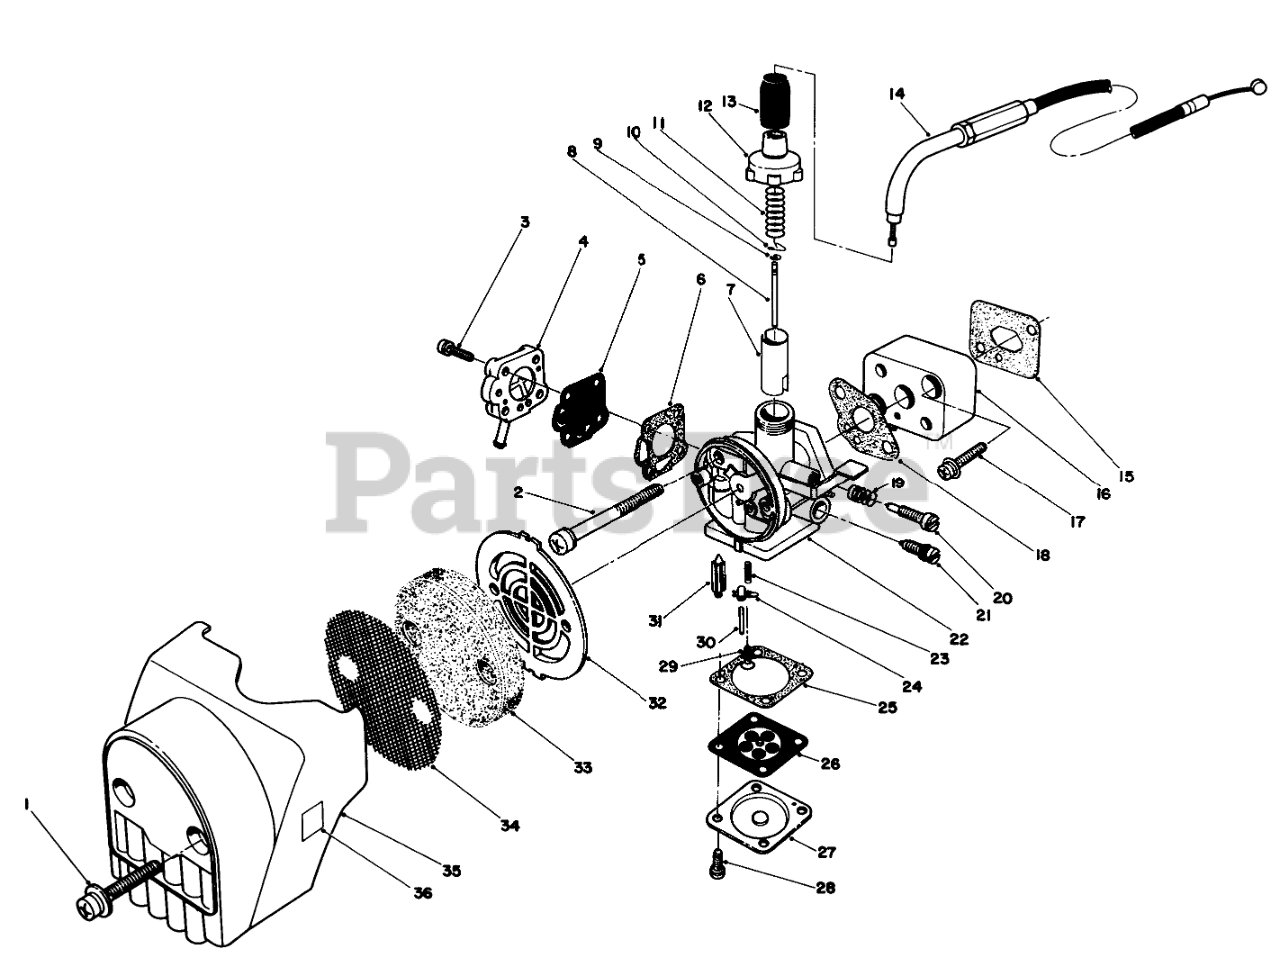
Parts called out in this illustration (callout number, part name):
1	Screw
2	SCREW W/ WASHER
3	SCREW W/ WASHER
4	Cover-Pump
5	Diaphragm-Pump
6	PUMP COVER GASKET
7	VALVE, THROTTLE
8	Jet Needle Assembly
9	Retainer
11	SPRING
13	AIR SEAL
14	WIRE, THROTTLE
15	GASKET,INSULATOR
16	INSULATOR
17	Screw & Washer
18	CARB. GASKET
19	ADJ. SCREW SPRING
20	SCREW
21	Needle-Main Jet
22	Carburetor Assembly (Incl. Ref. #3-13, 19-21, & 23-31)
23	VALVE SPRING
24	FLOAT ARM
25	DIAPHRAGM GASKET
26	Diaphragm-Main
27	DIAPHRAGM COVER
28	SCREW W/ WASHER
29	FLOAT SCREW
30	FLOAT PIN
31	FLOAT VALVE
33	ELEMENT
34	SCREEN
35	CLEANER COVER
36	CHOKE LABEL
